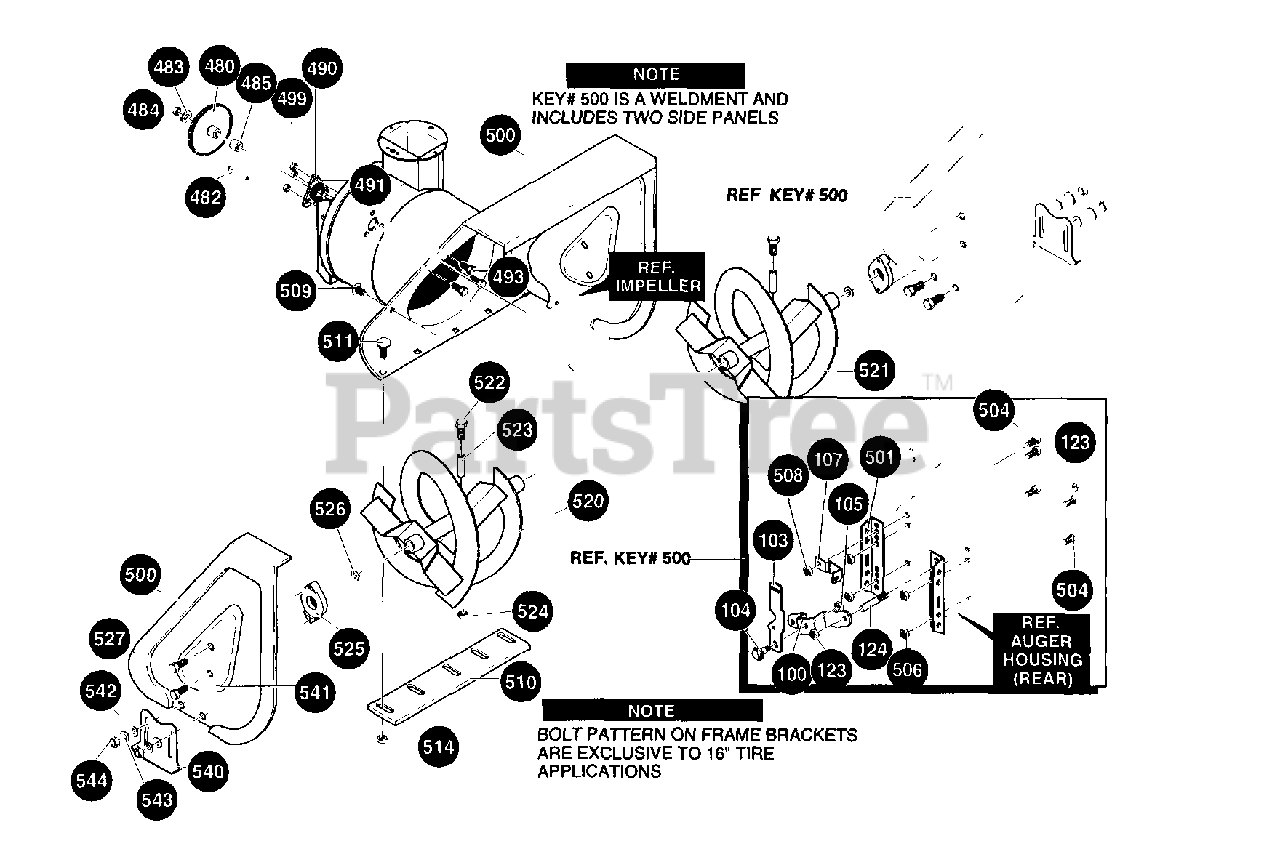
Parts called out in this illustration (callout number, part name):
100	PLATE, CLUTCH ARM M
103	BRACKET, IDLER
104	SH. BOLT, 3/8-16
105	NUT, 3/8-16 RGHXCTRLK
107	CABLE MTNG BRACKET
123	NUT, 3/8-16 RGHXCTRLK
124	STUD, BRAKE ARM
125	WASHER, REGXPTLK
480	PULLEY, V4L 8.40 OD
482	KEY, SQUARE
483	FLATWASHER .53 X 1.00 X .063
484	NUT, 1/2-20
485	SPACER, SLEEVE
490	RETAINER, BALL
491	BEARING, BALL
493	SCREW, 5/16-18 X .75
499	NUT, 5/16-18 WHIZ
500	HOUSING, ASSY
501	BRKT, MOUNT
504	SCREW, 3/8-16 X .75
506	NUT, 3/8-16 REGHXCTRLK
508	NUT, 3/8-16 REGHXCTRLK
509	PLUG, CHRISTMAS TREE
510	BLADE,SCRAPER
511	BOLT, 5/16-18 X .75
514	NUT, 5/16-18 HXWDFLLK
520	AUGER ASSY. LH
521	AUGER ASSY. RH
522	SCREW, 1/4-20 X 1.75
523	SPACER, SLEEVE
524	NUT, 1/4-20
525	AUGER SHAFT BEARING
526	FLATWASHER 1.005 X 1.31 X .035
527	SCREW, 5/16-18 X .75
540	SKID, HEIGHT ADJUST
541	BOLT, 5/16-18 X .75
542	FLATWASHER .344 X .69 X .065
543	WASHER, .328 X .60 X .09
544	NUT, 5/16-18 REGHEX
